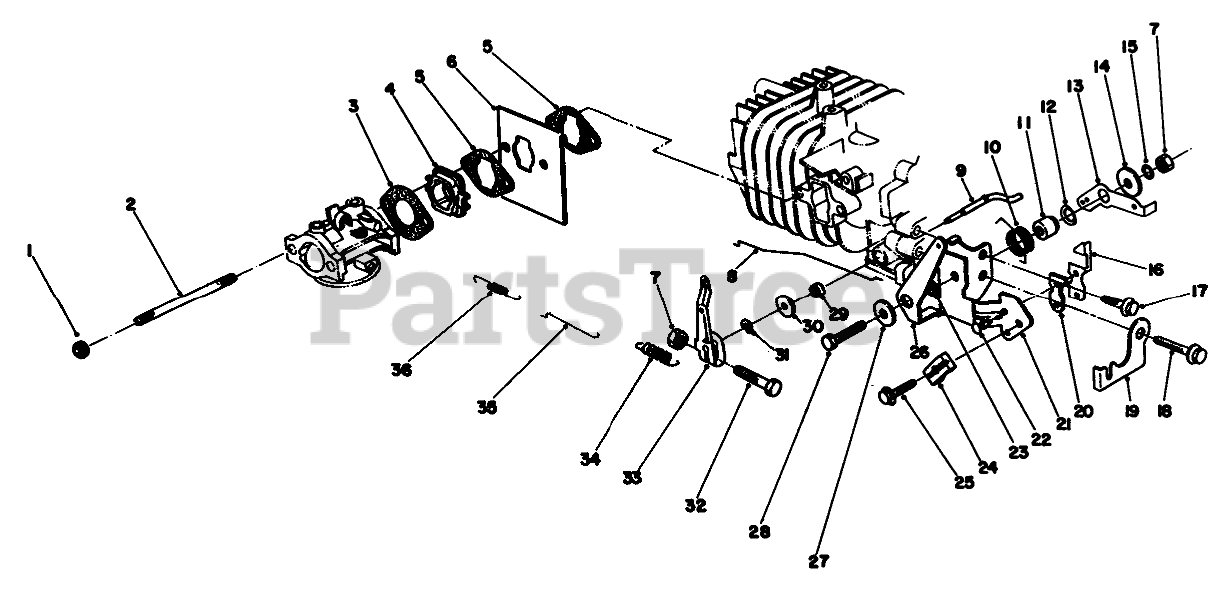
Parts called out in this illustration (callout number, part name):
1	NUT-LOCK
2	CARB STUD BOLT
3	GASKET-CARB
4	INSULATOR
5	GASKET
6	SHIELD
8	CHOKE ROD
9	Shaft-Govemor
10	Spring-Choke Control Lever
11	Gov Lever Spacer
12	Washer-Gov. Spring Lever
13	GOV SPRING LEVER
14	WASHER
15	LOCKWASHER
16	TERMINAL-KILL SWITCH
19	THROTTLE SUPPORT BRKT
20	INSULATOR-KILL SWITCH
21	Bracket-Throttle Control
22	KILL SWITCH RIVET
23	Spacer-Choke Control Lever
24	CLAMP-CABLE
26	LEVER-CONTROL, CHOKE
27	WASHER
29	SEAL-OIL
30	WASHER
31	E-RING
33	Lever-Throttle Control
34	GOVERNOR SPRING
35	ROD-CARBURETOR
36	SPRING
